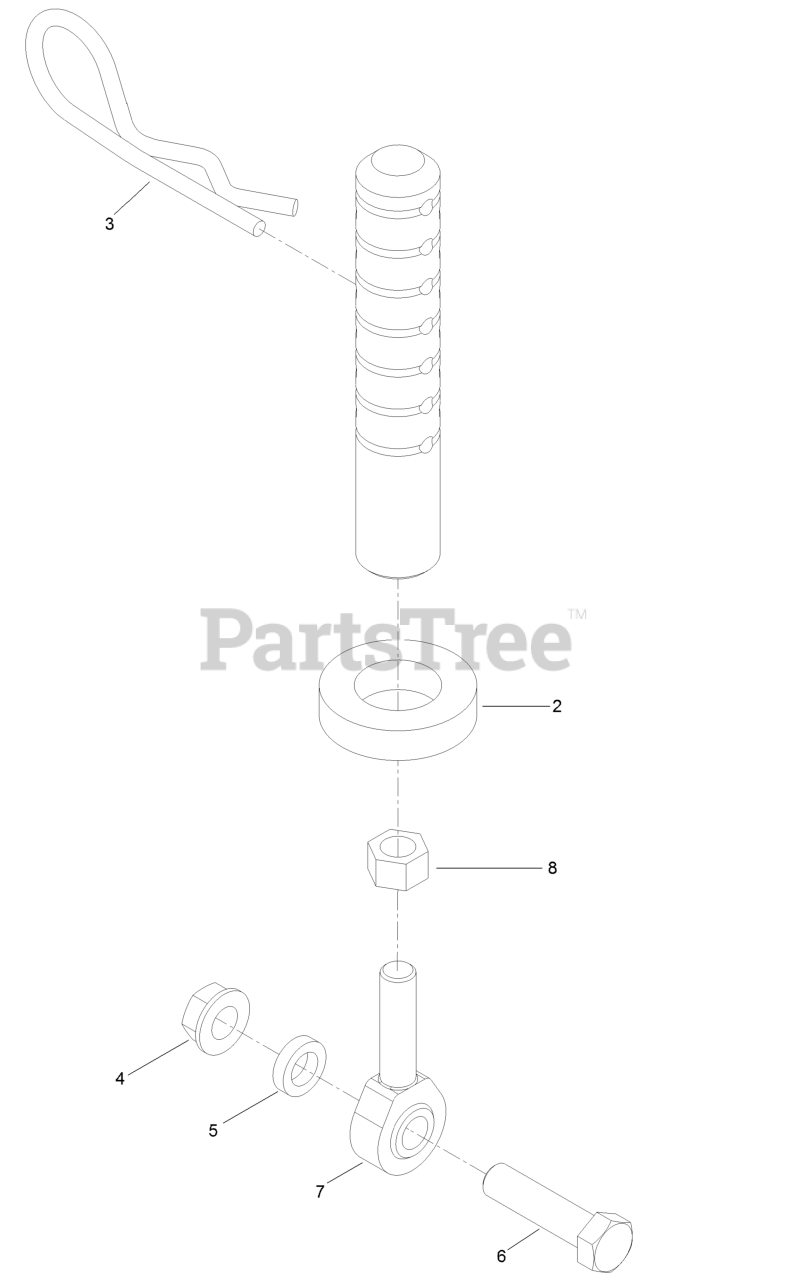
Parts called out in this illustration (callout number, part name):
2	Spacer-Deck Support
3	Pin-Cut Height
4	Nut-HHF, Whiz
5	Spacer-Idler
6	Screw-HH
7	Balljoint
8	Nut-HJ
